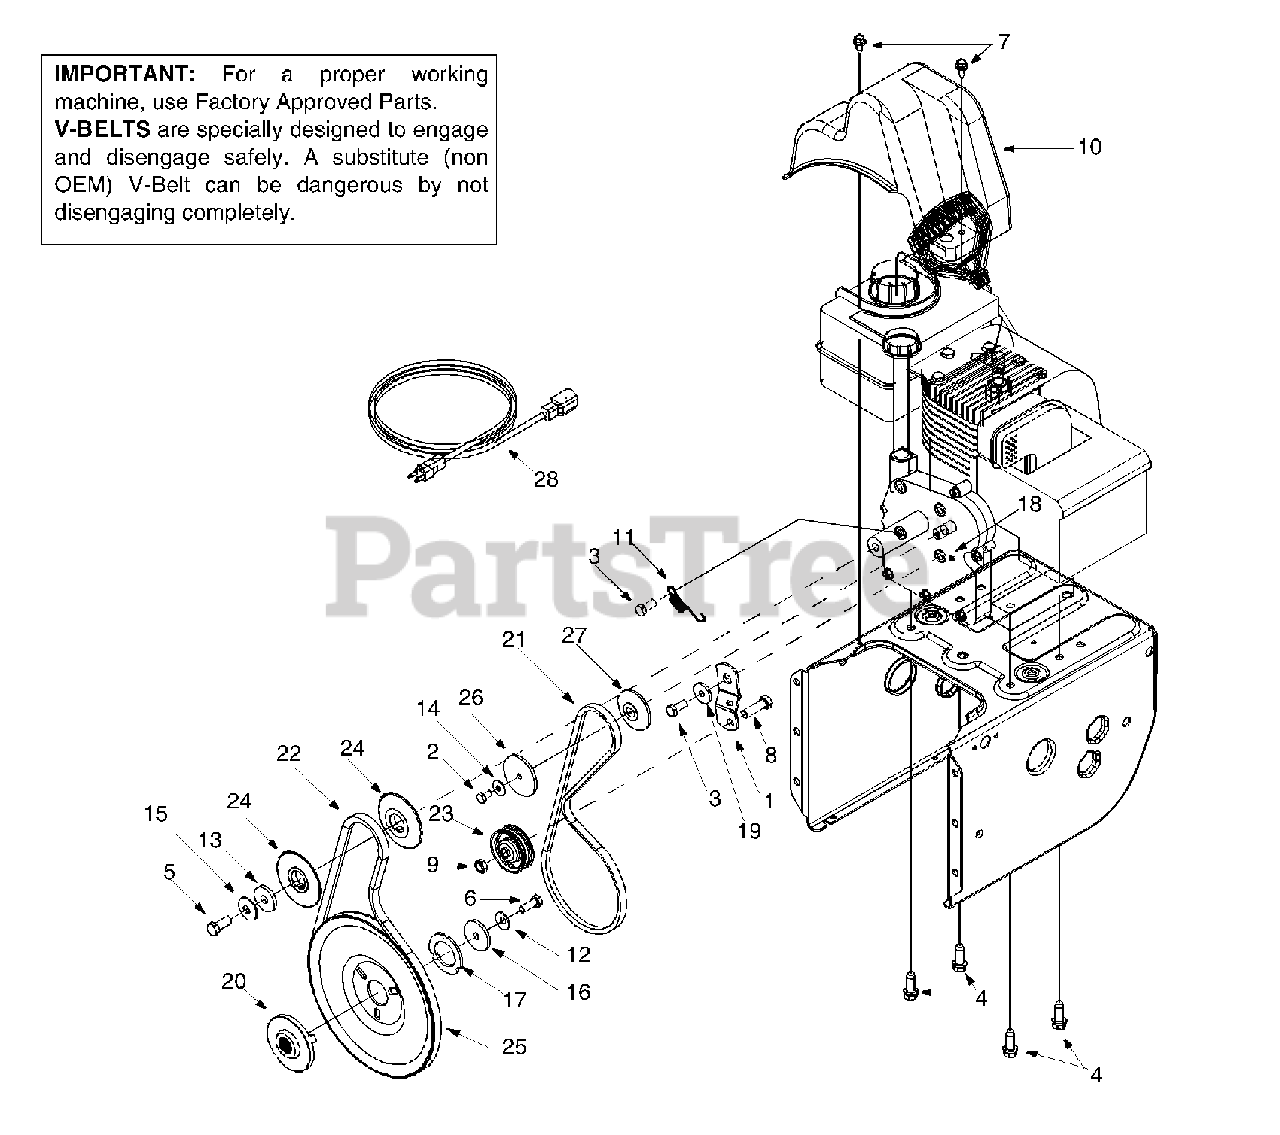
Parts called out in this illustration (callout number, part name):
3	Hex Bolt: Lock 5/16-24 x .750"
4	Self-Tapping Sems Screw
5	Hex Bolt 3/8-24 x .875"
6	Hex Bolt : Lock 5/16-24 x .875"
7	Self-Tapping Screw
8	Hex Screw 3/8-16 x 1.25"
9	Jam Nut
10	Belt Cover
11	Extension Spring
12	Beleville Washer
13	Flat Washer
14	Bell Washer
15	Bell Washer
16	Flat Washer
17	Special Washer
18	Grease
19	Shoulder Spacer
20	Pulley: Adapter
21	V-Belt
22	Belt
23	Idler: Flat
24	Pulley: Half
25	Auger Pulley
26	Pulley Half
27	Pulley Half
28	Extension Cord
